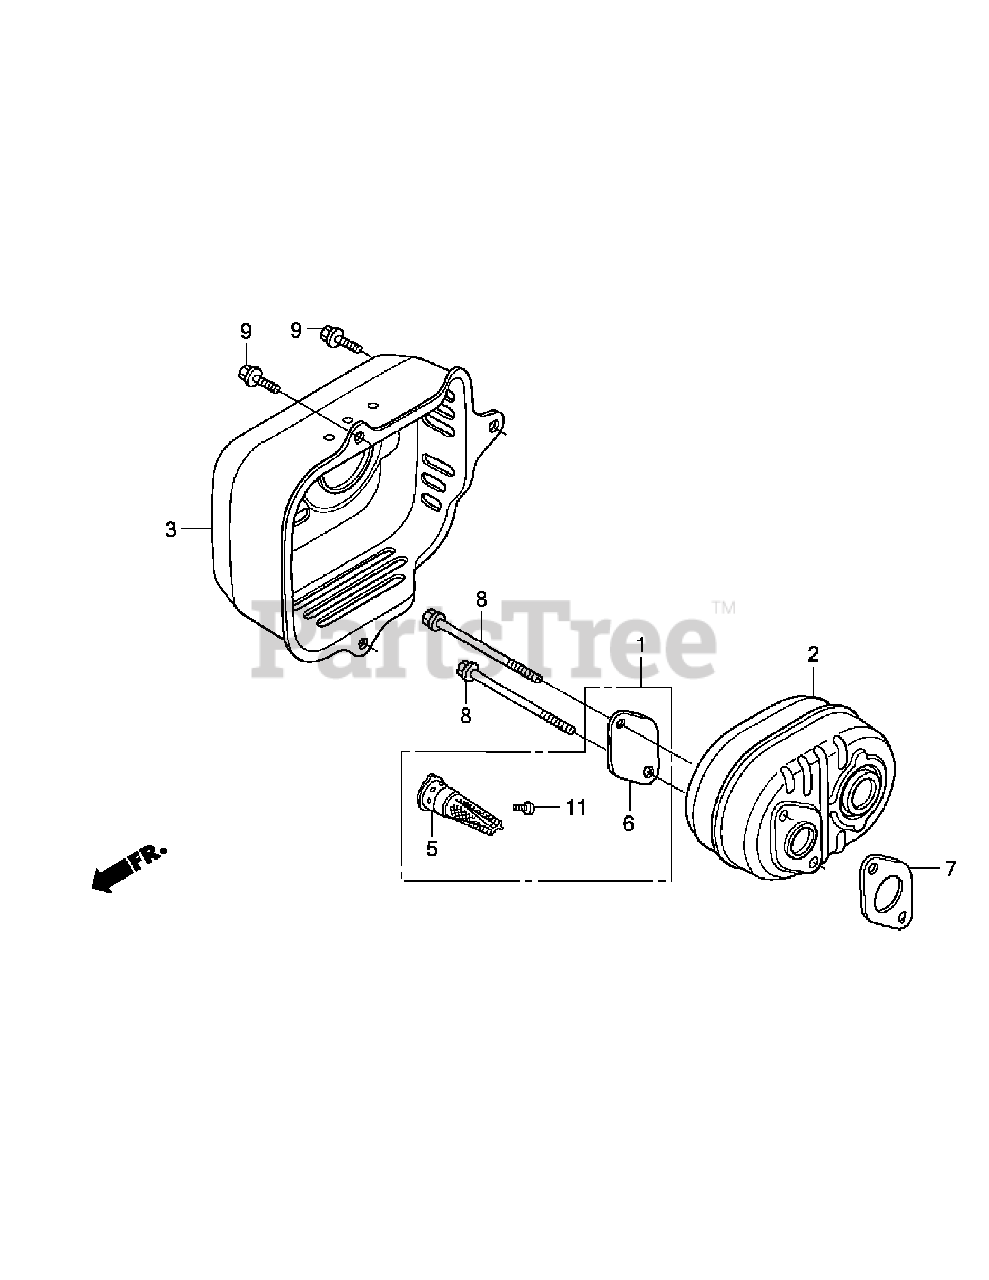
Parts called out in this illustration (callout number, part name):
1	Spark Arrester Kit
3	Muffler Protector
5	Spark Arrester
6	Arrester Number Plate
7	Muffler Gasket
8	Flange Bolt, 6 x 79
9	Flange Bolt, 6 x 12
11	Tapping Screw, 4 x 6
